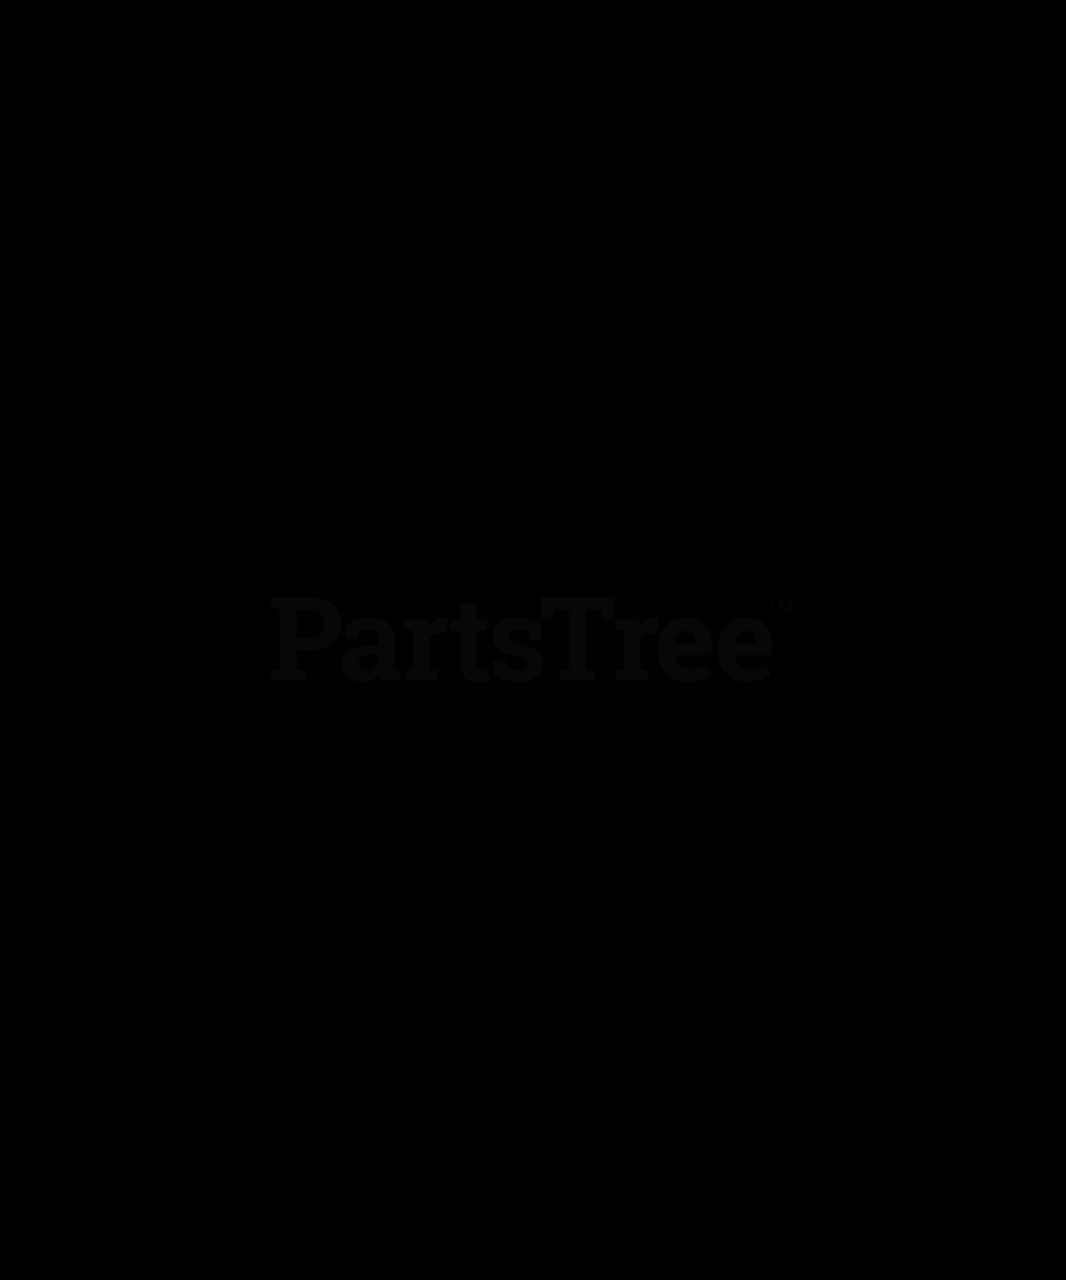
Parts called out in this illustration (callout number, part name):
2	Diesel Belt Guard
3	Screw, Tapping .38-16 x .75 Hex Washer Head
4	Nut, Spin Lock, Flange .312-18
5	Latch, Rubber
6	Screw, Machine 10-24 x .50 Hex Washer Head
7	Screw, Machine 10-24 x 1.50 Hex Washer Head
8	Bumper, Rubber
9	Bumper, Weldment, Rear Diesel
10	Screw, Tapping .25-20 x .50 Hex Washer Head
11	Guard, Radiator Cap
12	Nut, Locking Top Flange .25-20
13	Washer, Flat Steel .281 x .62 x .065
14	Guard, Hood
15	Bolt, Round Head Square Neck .25-20 x .50 Grade 5
16	Bolt, Hex .38-16 x 2.75 Grade 5
17	Nut, Locking Top Flange .38-16
18	Washer, Flat Steel .406 x .812 x.065
19	Dam, Left Side Foam Air
20	Dam, Right Side Foam Air
